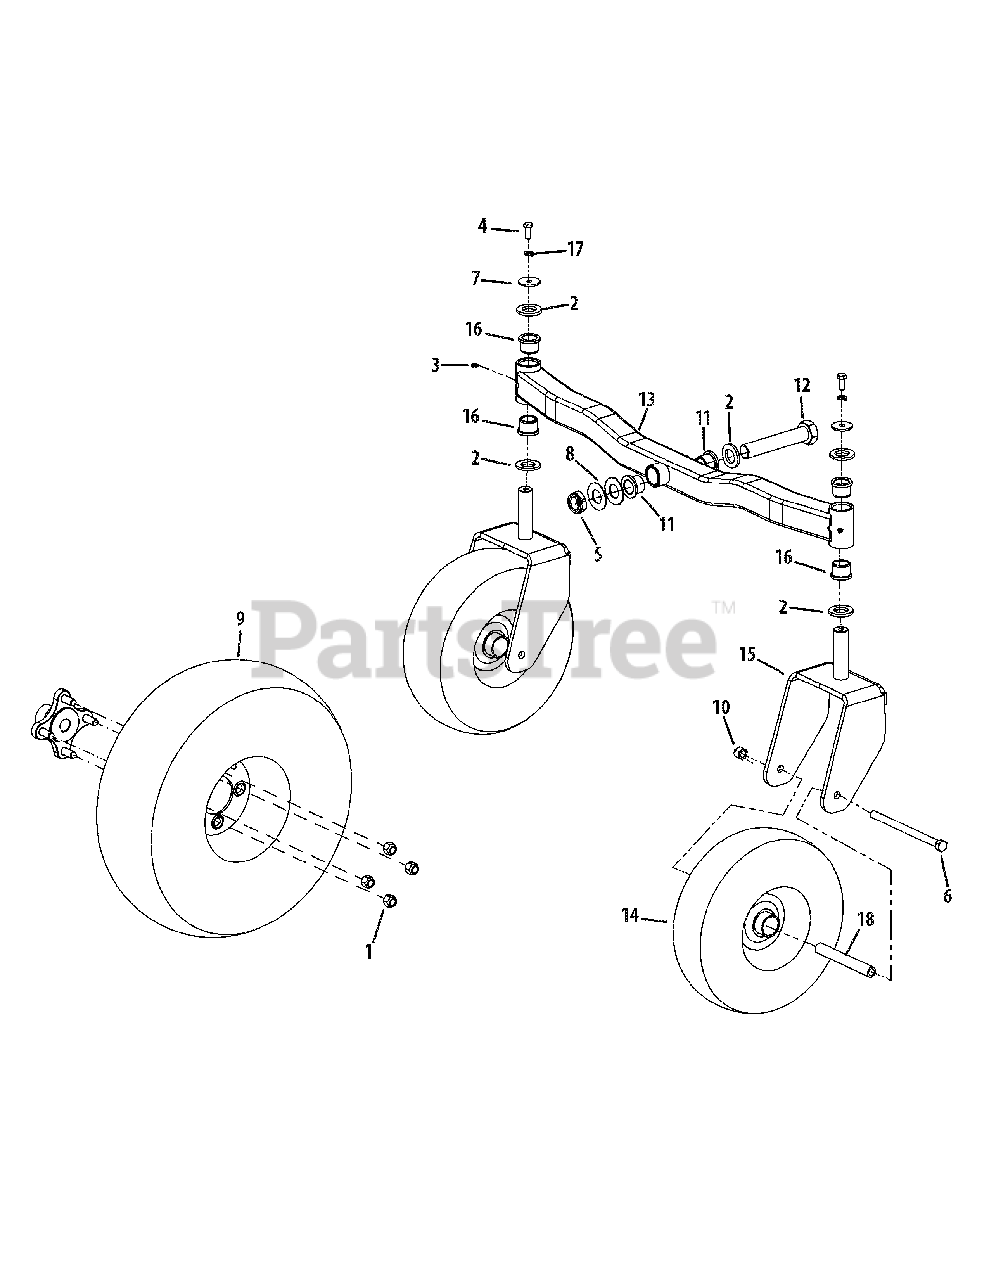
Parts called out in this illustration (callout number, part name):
1	Lug Nut, 1/2-20
2	Washer, 1.00 x 1.75 x .172
3	Grease Fitting, 1/4-28
4	Hex Screw, 3/8-16 x .880
5	Jam Nut, 1-14
6	Hex Screw, 1/2-20 x 7.50
7	Washer, .390 x 1.50 x .122
8	Washer, 1.00 x 2.00 x .075
9	Wheel Assy., 20 x 8-10 (48" Deck)
9	Wheel Assy., 20 x 10.00 x 10 (54" Deck)
10	Nylock Nut, 1/2-20
11	Flange Bearing, 1.001 x 1.25
12	Hex Screw, 1-14 x 5.5
13	Front Axle Weldment
14	Wheel Assembly, 13 x 5 x 6
14	Roller Bearings
14	Retainer Bushing
15	Castor Wheel Mount Bracket Assy.
16	Flange Bearing, 1.000 x 1.254
17	Lock Washer, 3/8
18	Spacer, .51 x .75 x 5.825
